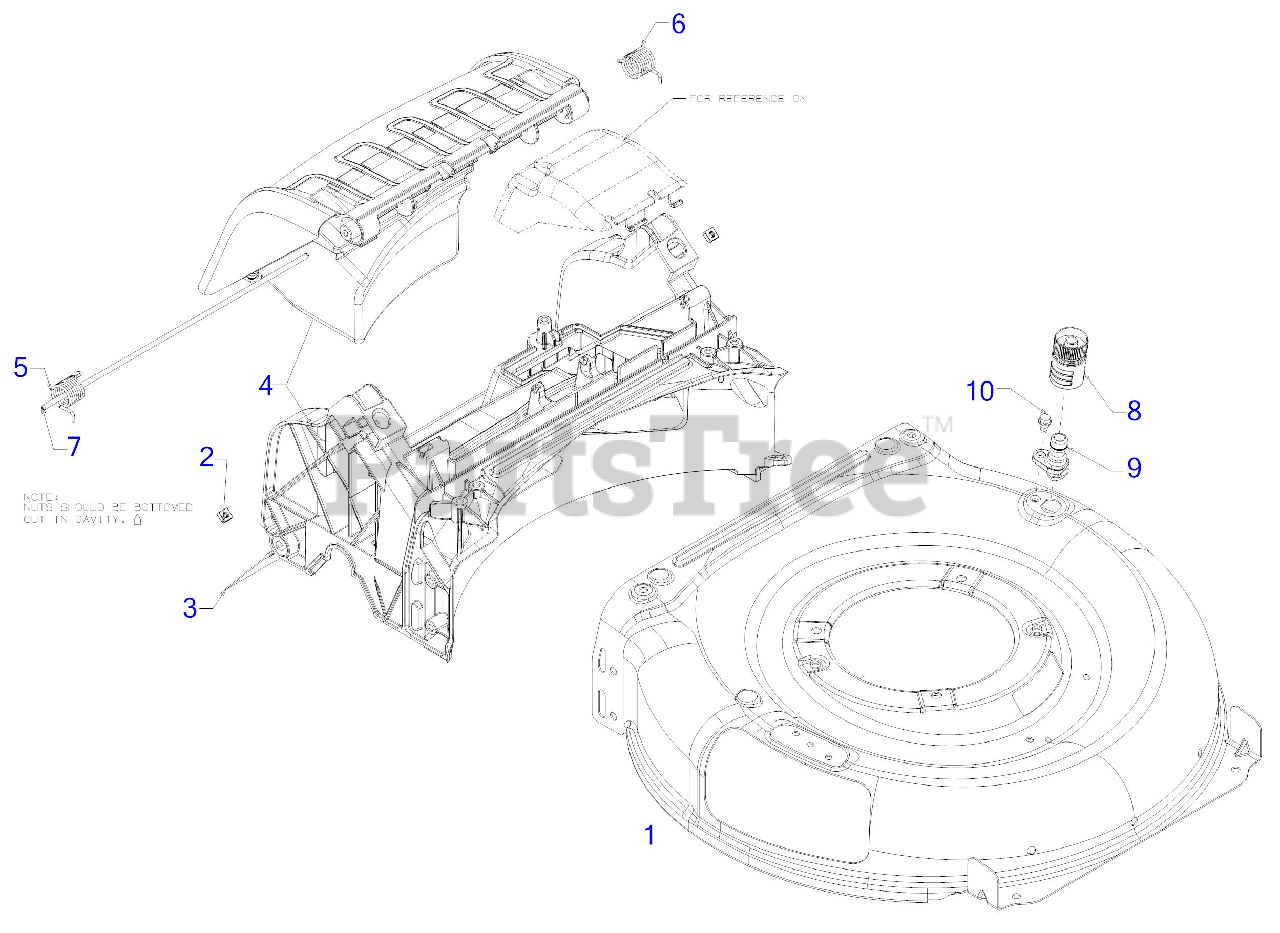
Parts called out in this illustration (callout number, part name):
2	SQUARE NUT 1/4-20
3	TRAILSHIELD
4	REAR BAG BAFFLE ASSEMBLY
5	TORSION SPRING (RH)
6	TORSION SPRING (LH)
7	REAR DOOR PIVOT ROD
8	WATER NOZZLE
9	DECK WASH NOZZLE
10	SHOULDER SCREW 1/4-20 x .50
